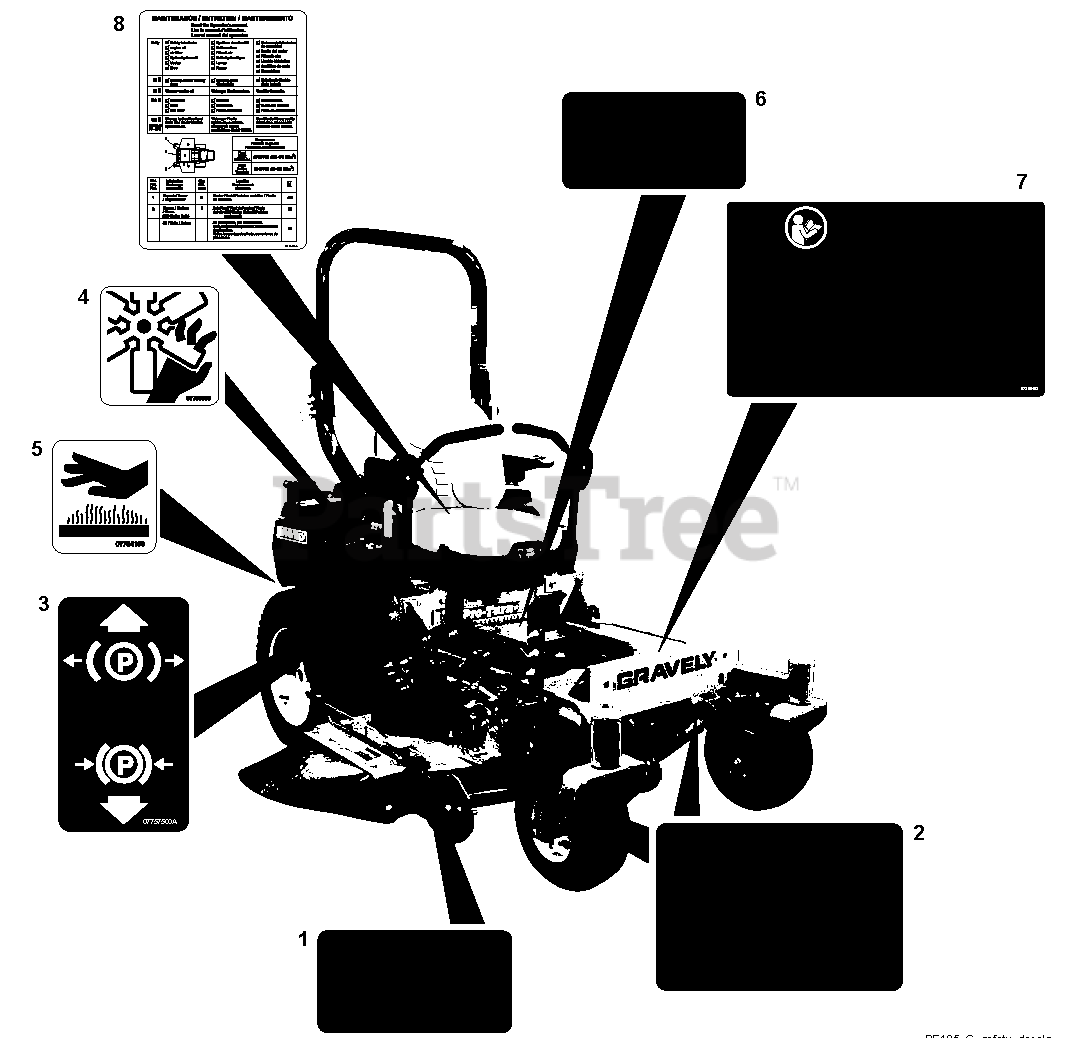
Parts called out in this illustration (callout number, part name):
1	Decal, Safety Deck Guarding
2	Decal, Safety Mower Deck
3	Decal, Parking Brake Lever
4	Decal, Danger Fan
5	Decal, Hot Surface
6	Decal, Safety Guarding
7	Decal, Main Safety Commercial
8	Decal, Maintenance Instructions
